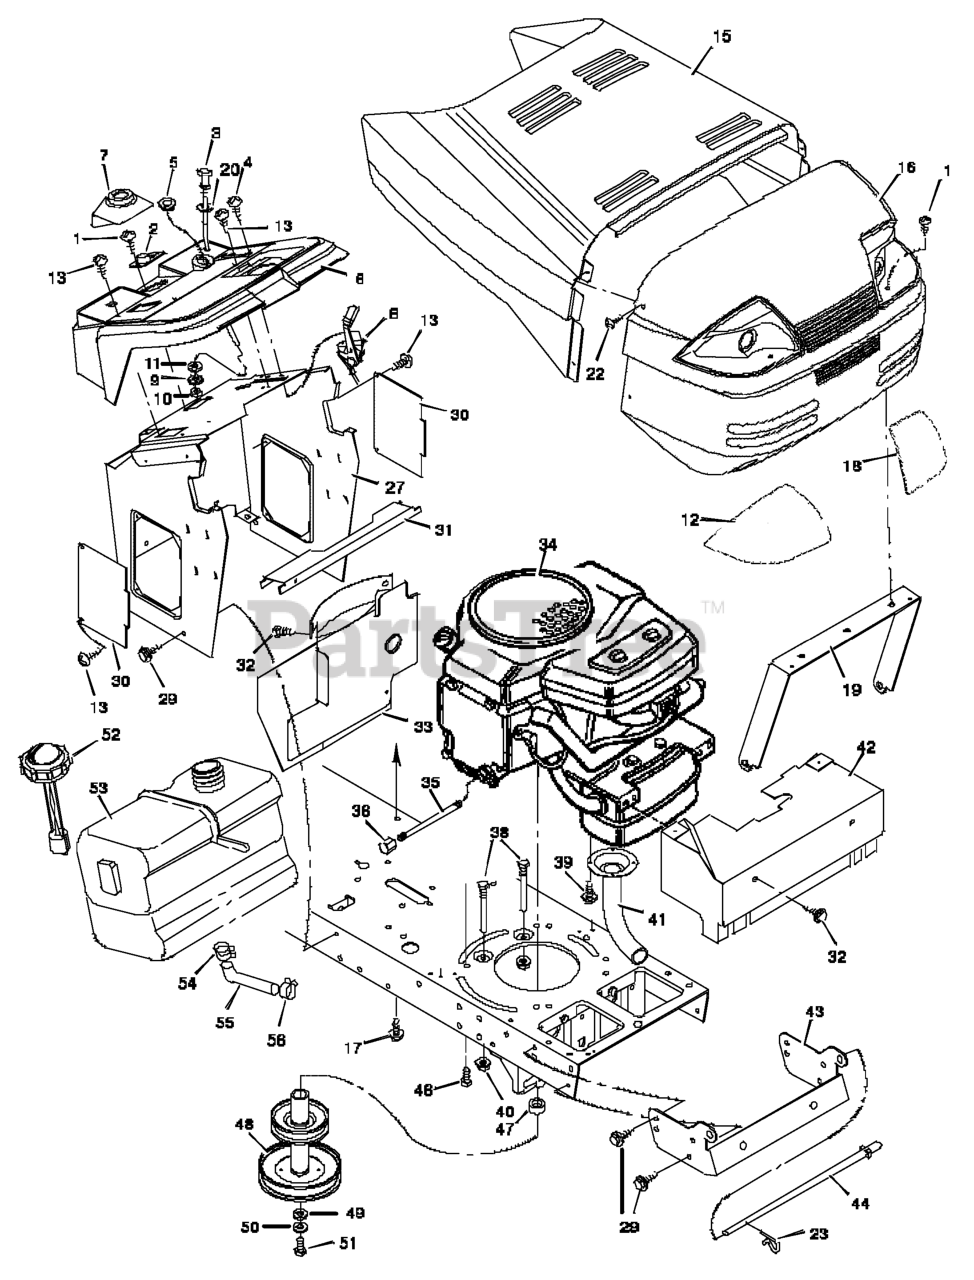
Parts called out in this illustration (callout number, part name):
2	Bearing, Steering Post
3	Cable, Choke
5	Bushing
7	Support, Bellows
8	Throttle Control
9	Lockwasher
10	Nut, Hex
12	Lens, Right
13	Screw
16	Grille
18	Lens, Left
19	Brace, Grille
20	Washer
23	Pin, Hair
27	Console Assembly
30	Panel, Side Access
31	Support, Fuel Tank
32	Screw
33	Baffle, Rear Heat
34	Engine *
35	Oil Drain Extension
36	Oil Drain Cap
38	Guide, Belt
40	Locknut, Flange
41	Pipe, Exhaust
42	Shield, Heat
43	Support, Grille
44	Rod, Pivot
46	Bolt, Hex
47	Spacer, Engine
48	Pulley Assembly, Stack
50	Lockwasher
51	Bolt, Hex
52	Cap, Fuel
53	Fuel Tank
54	Clamp, Hose
55	Fuel Line
56	Clamp, Hose
